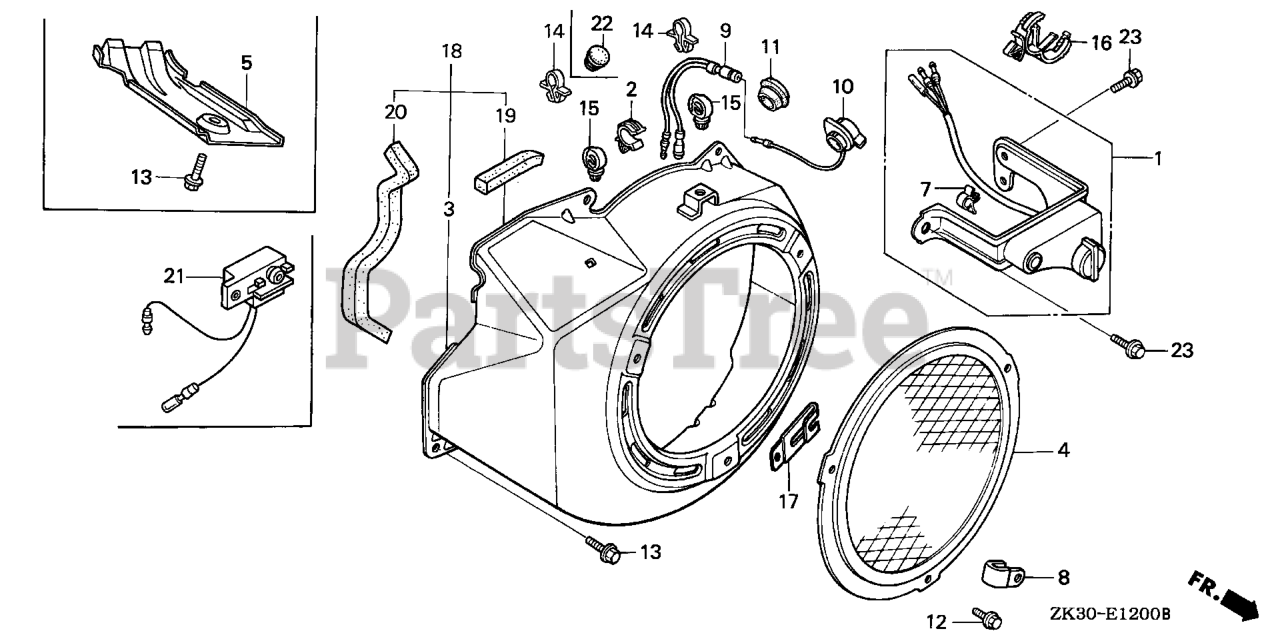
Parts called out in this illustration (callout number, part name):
2	CLIP, TUBE
3	COVER, FAN *NH1* (BLACK)
11	GROMMET, DRAIN HOLE
13	BOLT, FLANGE (6X12) (CT200)
